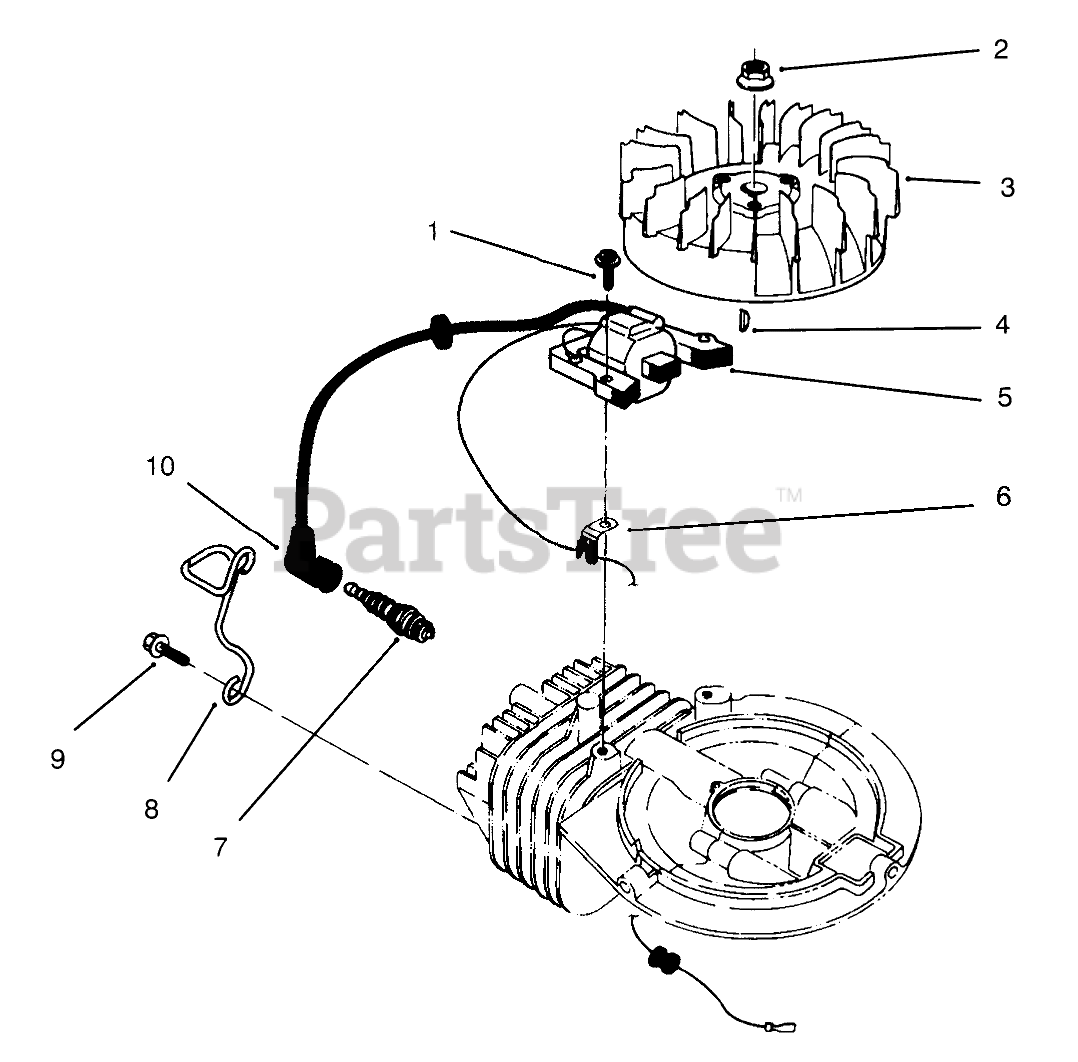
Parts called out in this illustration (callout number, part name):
1	SCREW
3	FLYWHEEL
5	COIL-MAGNETO
6	CLAMP
7	Sparkplug
8	PROTECTOR-PLUG
9	SCREW
10	CAP-SPARKPLUG
